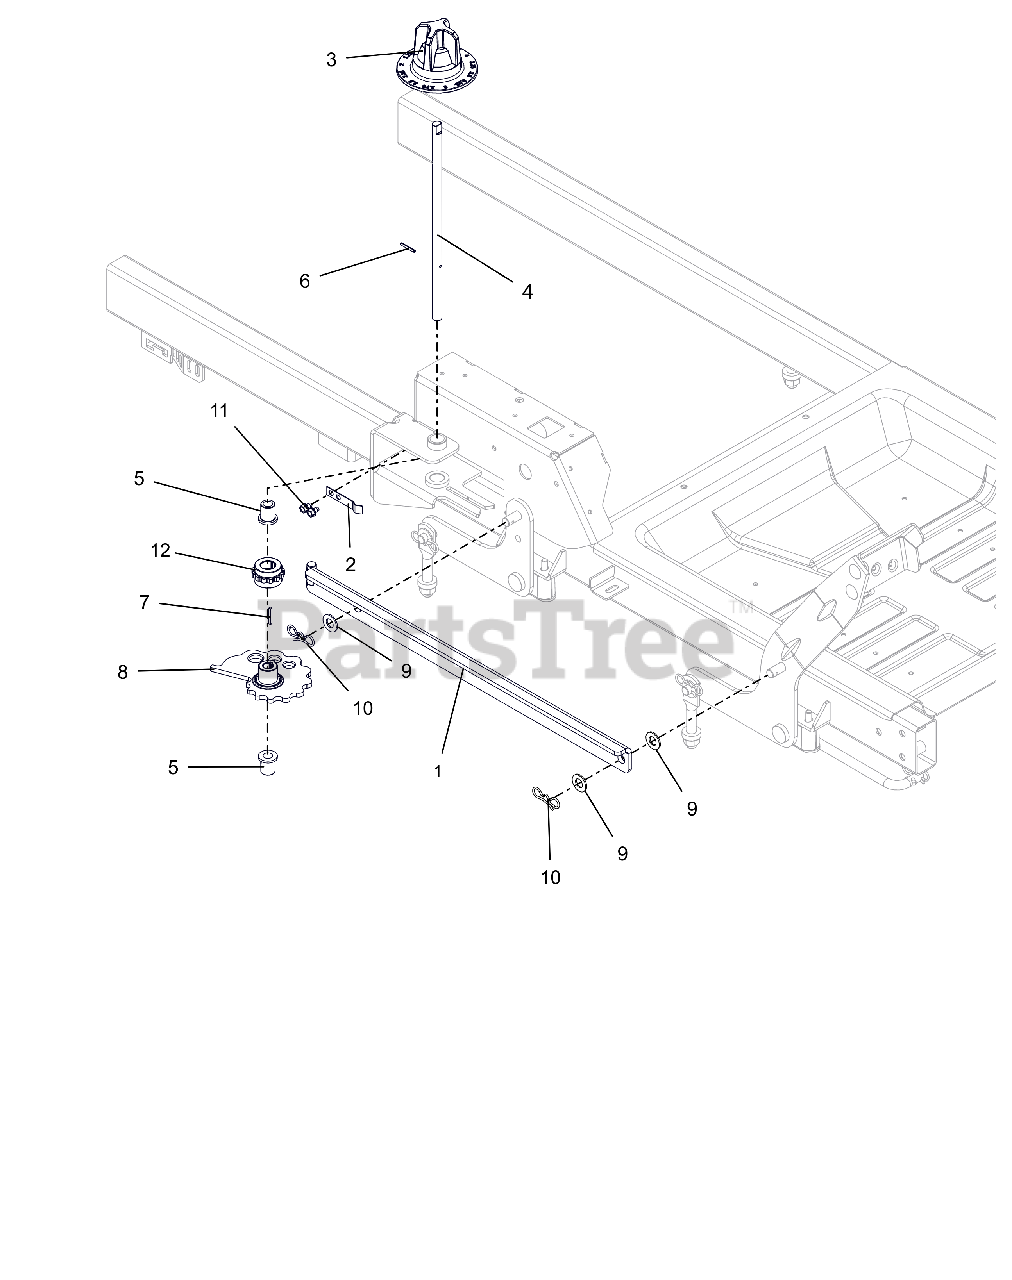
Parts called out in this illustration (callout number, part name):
1	WLDMT, HOC LINK
2	ARM, HOC DETENT
3	KNOB, HOC DIAL
4	SHAFT, HOC CAM IKON
5	BSHG-FLG, .503X.750X.875X1.00
6	PIN-ROLL .125X1.00
7	KEY, 1/8 X 1/8 X 1.0
8	CAM, HOC (PM)
9	WSHR-FL-NYL .518X1.000X.080
10	PIN, BOWTIE .091X1.875 ZCC
11	SCR,TAP .25-20X.375 HWH TR ZCC
12	GEAR, HOC INDEX
